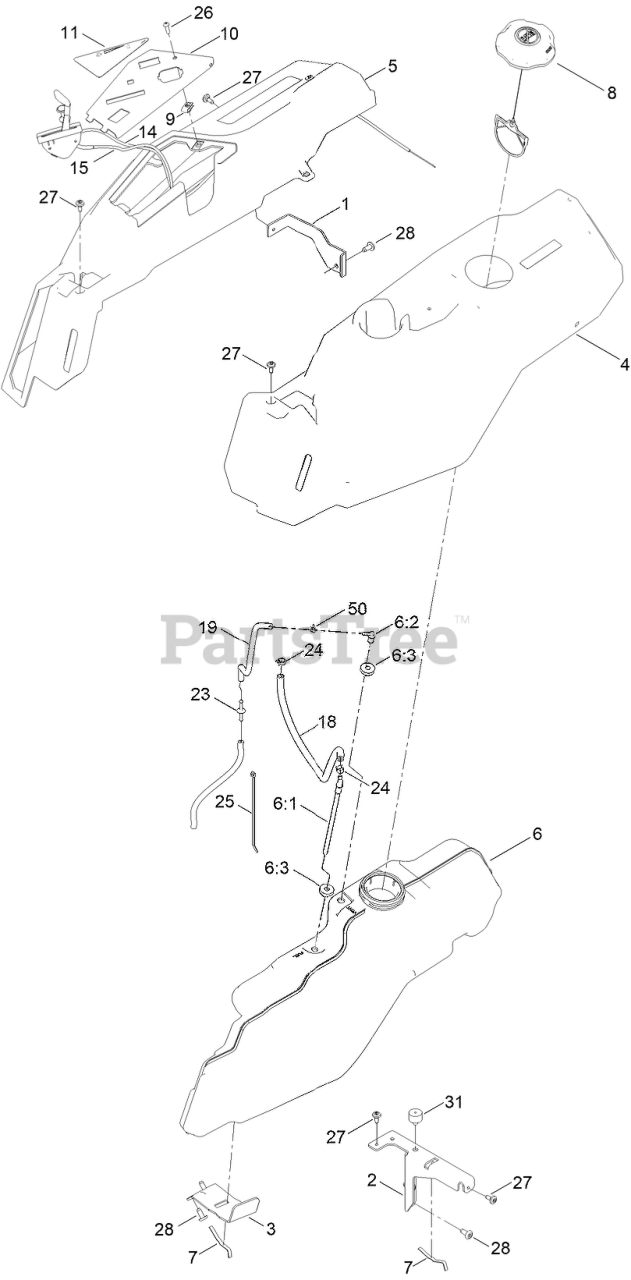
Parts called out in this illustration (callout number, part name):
1	BRACKET-POD
2	SUPPORT-POD, LH
3	SUPPORT-TANK, FUEL
4	POD-LH
5	POD-RH, MYRIDE
6	TANK-FUEL ASM
6:1	CONNECTOR-ELBOW, 90 DEG
6:2	FITTING-ELBOW 90
6:3	BUSHING
7	SPRING
8	CAP-FUEL, RATCHETING
10	PANEL - CONTROL
11	DECAL-PANEL, CONTROL
14	CABLE-THROTTLE
15	CABLE-CHOKE
18	HOSE-FUEL
19	HOSE-FUEL
23	ADAPTER ORIFICE
24	CLAMP-HOSE
25	TIE-CABLE
26	SCREW-PRH
27	SCREW-SHOULDER
31	BUMPER-GROMMET
50	CLAMP-HOSE
